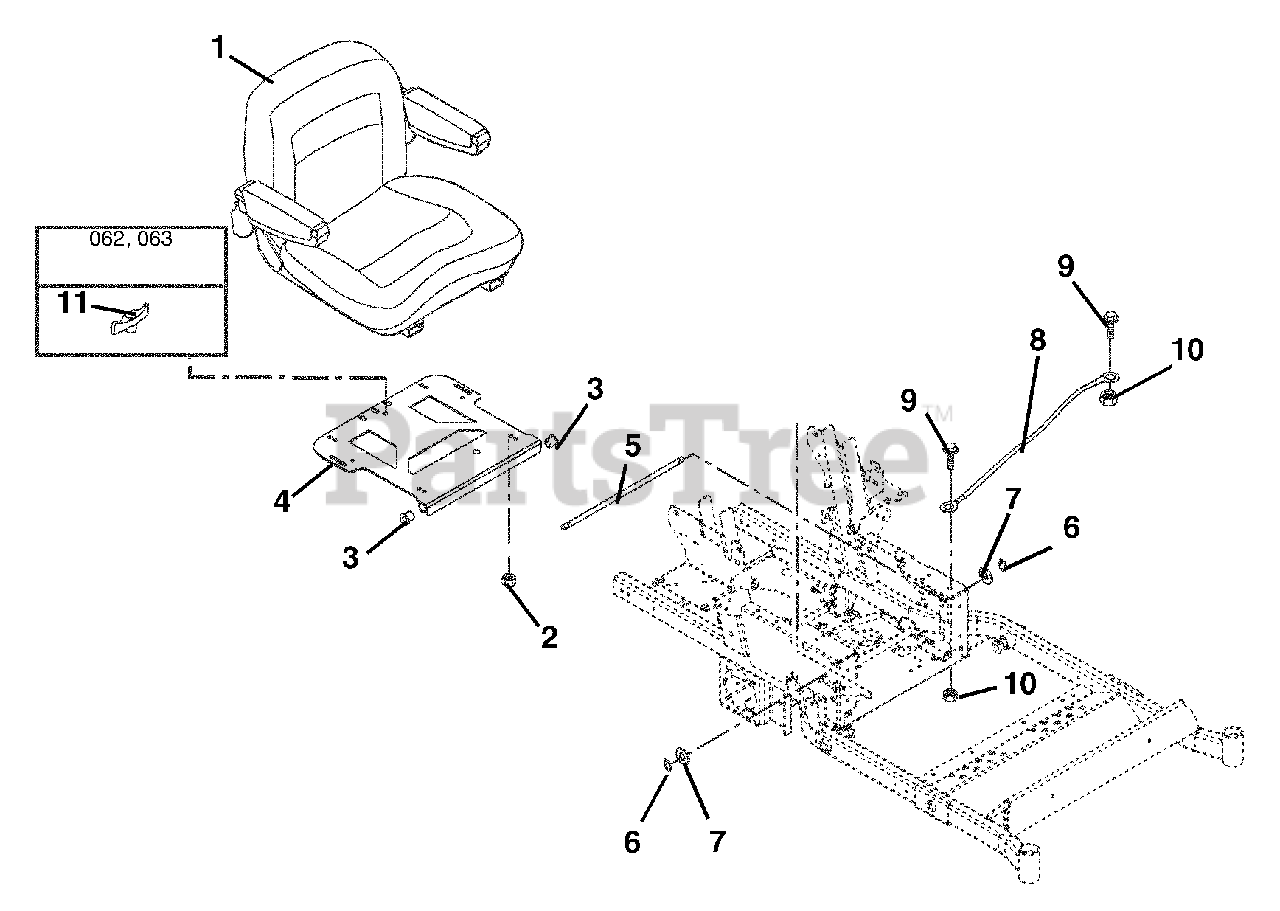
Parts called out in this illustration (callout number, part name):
1	SEAT, MILSCO XB180 - ZOOM
2	@NUT-LK-TOP-FLG .31-18 YWZC
3	BSHG-FLG .515X.750X.745X1.00NY
4	WMT, SEAT PIVOT MOUNT
5	ROD, SEAT FRAME PIVOT
6	RG-RTNG-EXT .500X.050 (SNAP)
7	WSHT-THRST 1.140X1.5X.200
8	CBL,HOOD
9	@BLT-HEX .25-20X.75 GR5 YWZC
10	@NUT-LK-TOP-FLG .25-20 YWZC
11	KNOB - WING .312-18 UNC
